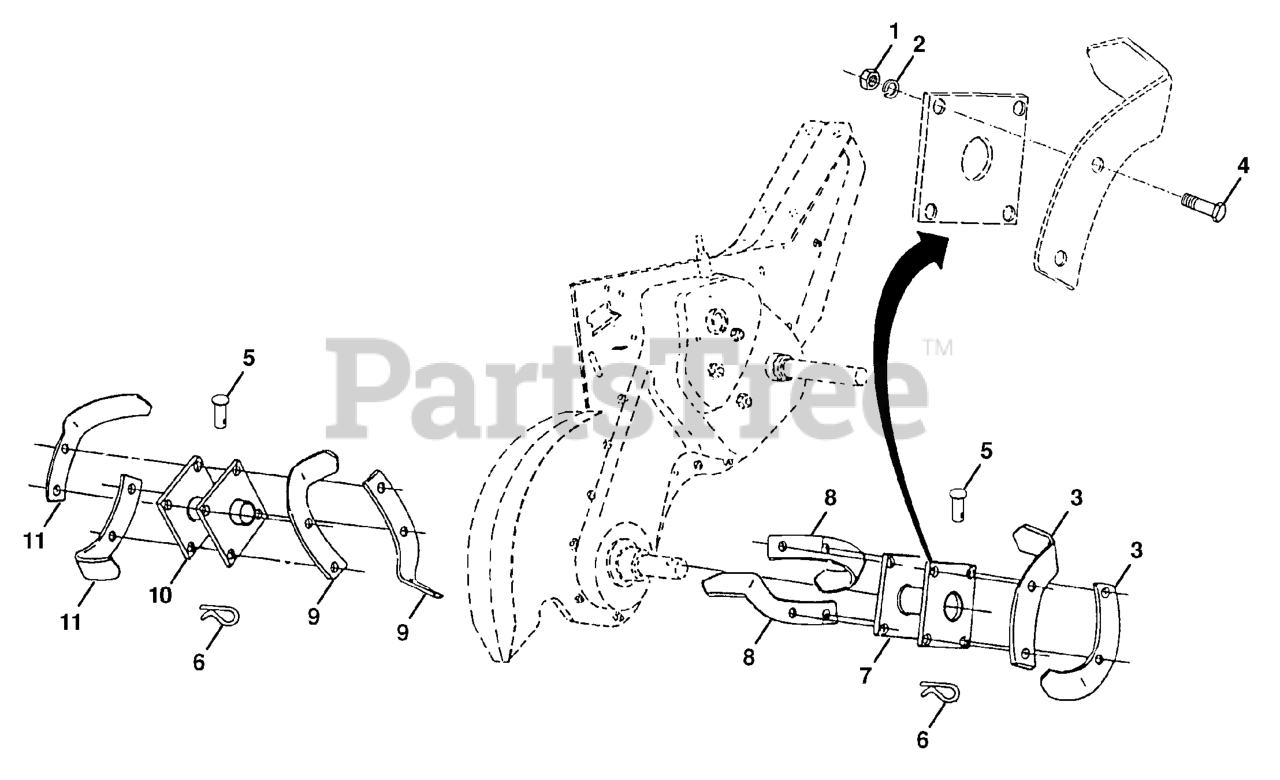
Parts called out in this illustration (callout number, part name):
1	NUT
2	WASHER, LOCK 3/8
3	TINE TI
4	BOLT.HEX.001X20.37-24X1.ZINC
5	PIN RETAINING SCREW
6	SPRING RETAINER
7	HUB.ASM.RH.14".BLACK.TILLER
8	TINE.RH.12"(72R)
9	TINE.LH.12"(72L)
10	HUB.&.PLATE.LH.TILLER.BLACK
11	TINE TI
